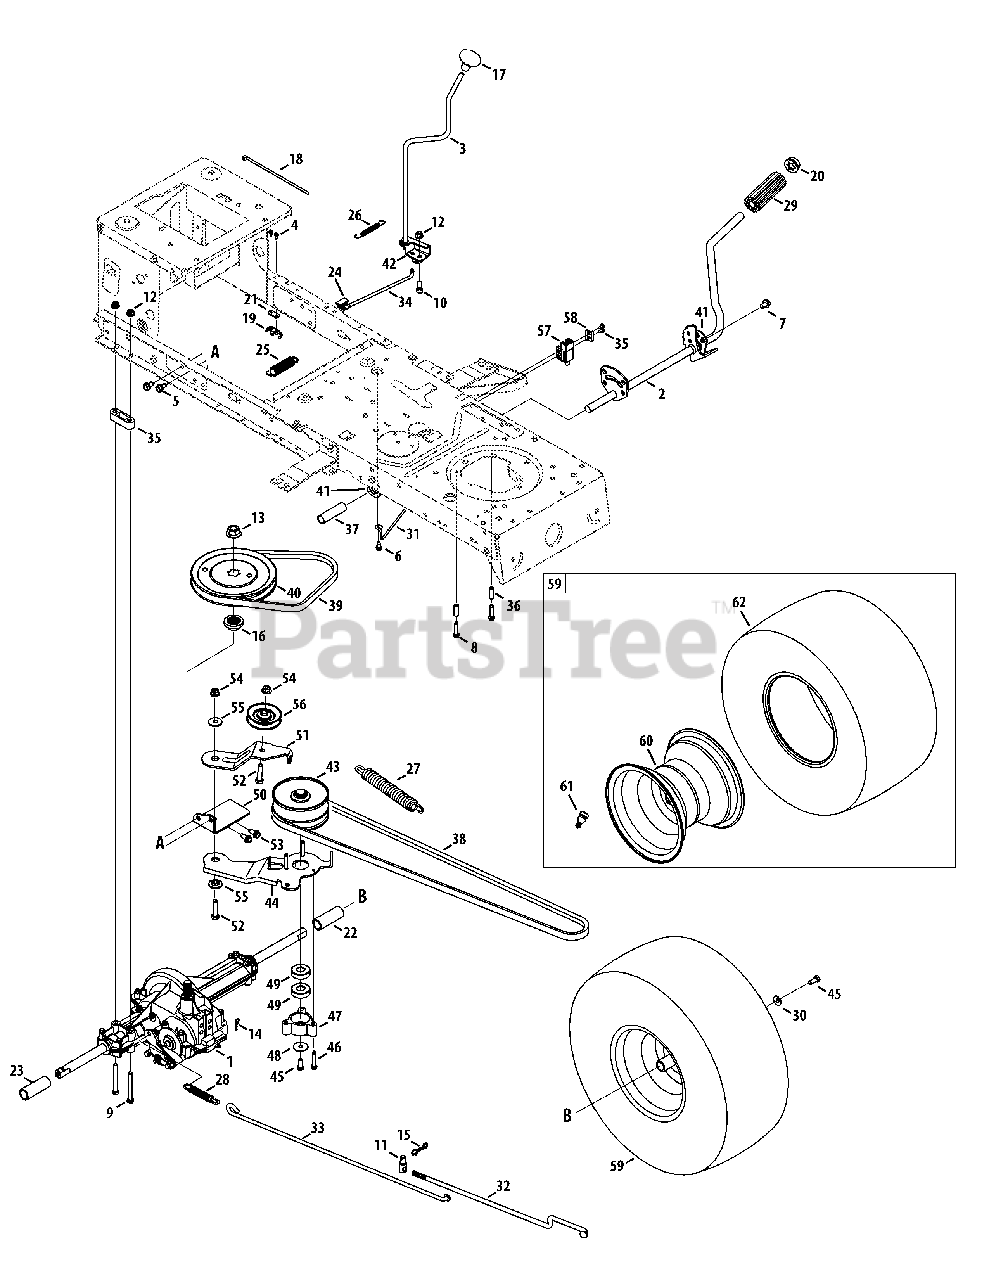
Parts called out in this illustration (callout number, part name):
1	Transmission Drive Assembly
2	Pedal Assembly
3	Shaft Lever Assembly
4	Screw, 8-18:0.500
5	Screw, 5/16-18 x .750
6	Screw, 1/4-20 x 0.500
7	Screw, 5/16-18 x 0.625
8	Screw, 1/4-20 x 1.250
9	Hex Screw, 5/16-18 x 2.75
10	Hex Screw, 5/16-18 x .75
11	Ferrule, 3/8-24 X .375 DIA.
12	Flangelock Nut, 5/16-18
13	Flange Nut, 9/16-18
14	Cotter Pin INT- .125 DIA
15	Bow-Tie Cotter Pin
16	Pulley Hub, 5/8 SPLINE
17	Shift Knob
18	Cable Tie
19	Short Spring Switch
20	Push Cap, 5/8
21	Plate Insulator Nut
22	Sleeve, .758 x .821 x 3.3125
23	Sleeve, .758 x .821 x 2.4375
24	Shift Bearing Plate
25	Spring Extension, .80 OD x 3.28 LG
26	Spring Extension, .38 OD x 3.25 LG
27	Spring Extension, .94 OD x 6.75 LG
28	Spring Extension, .59 OD x 4.00 LG
29	Foot Pad, 4.0 LONG
30	Bell Washer, .340 x .872 x .060
31	Belt Keeper Rod
32	Variable Speed Control Rod
33	Brake Rod
34	Shift Rod
35	Shoulder Screw, #10-32 x .500
36	Spacer, .260 x .375 x 1.030 LG
37	Spacer, .640 ID x .76 OD x 2.63
38	V Belt, 5L: 70.90 POLY
39	V Belt, 5L: 35.25 POLY
40	Trans. Pulley
41	Pedal Support Bracket
42	Shaft Adjust Bracket
43	Variable Speed Pulley Assembly
44	Bracket Assembly
45	Hex Screw, 5/16-24 x .750
46	Screw, 1/4-20 x 1.500
47	Bearing Cup
48	Flat Washer, .330 x 1.25 x .06:HT
49	Ball Bearing, 17 x 40 x 12
50	Transmission Bracket Assembly
51	Idler Bracket Assembly
52	Hex Screw, 3/8-16 x 1.75
53	Screw, 5/16-18 x 0.750
54	Flange Lock Nut, 3/8-16
55	Shoulder Spacer, .625 ID x .169
56	Idler Pulley
57	Switch Interlock
58	Plate Switch
59	Wheel Assembly, 20 x 8 x 8
60	Rim Assembly
61	Valve Stem
62	Tire, 20 x 8 x 8 Rd. Shoulder
